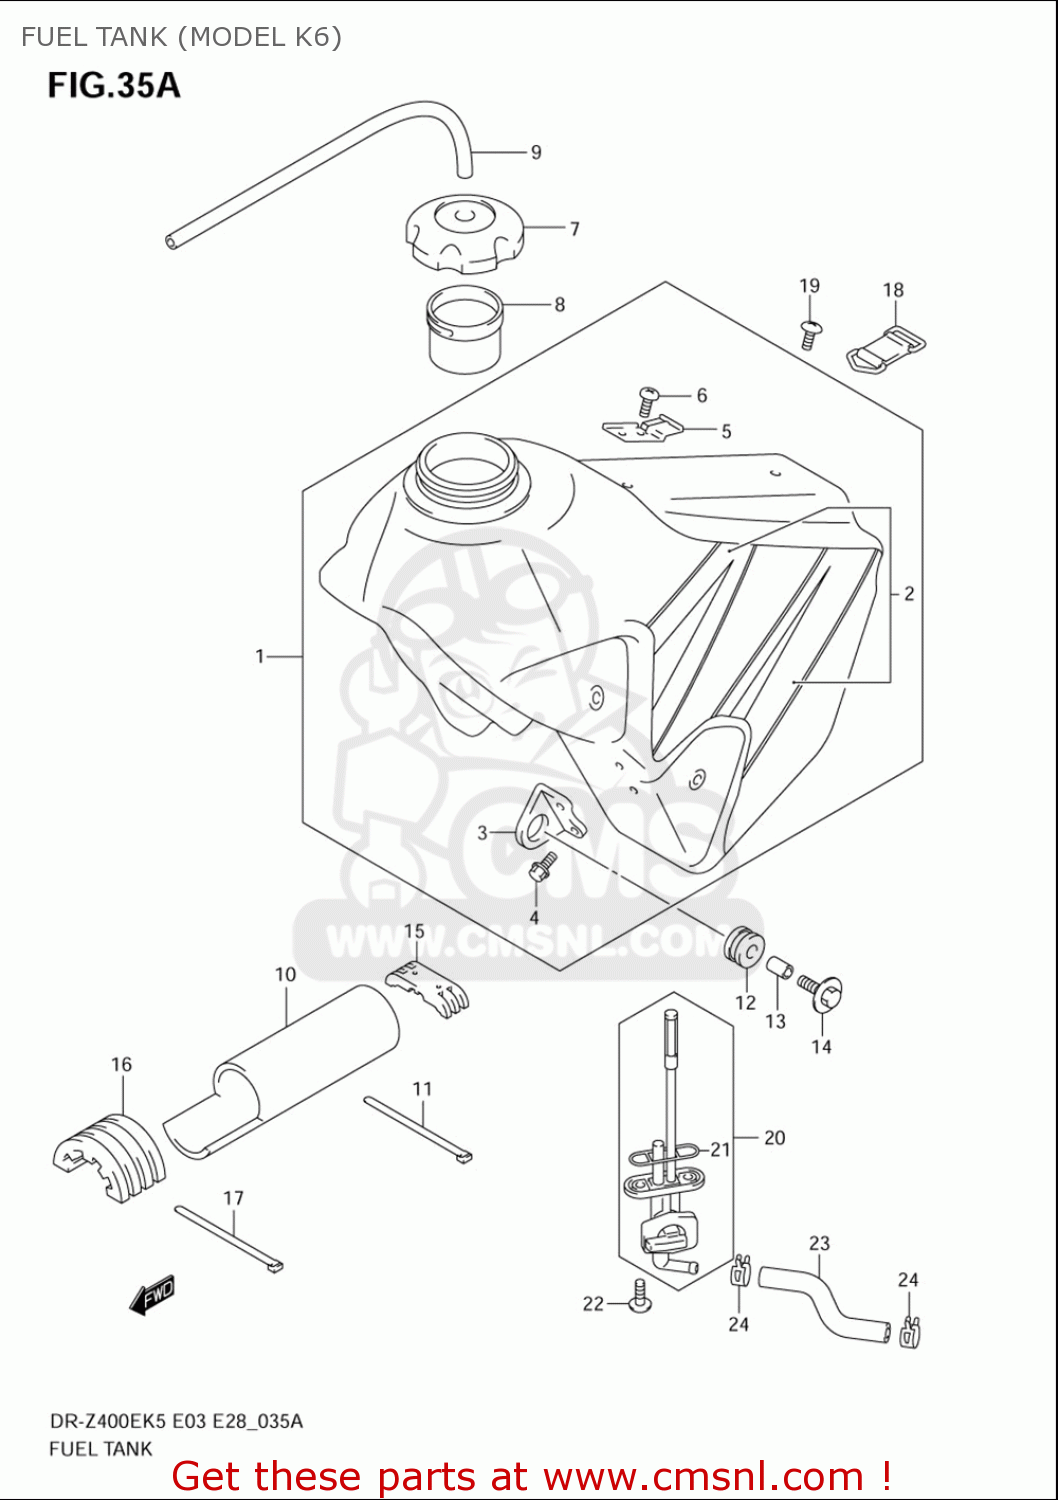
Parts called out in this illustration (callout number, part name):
1	TANK ASSY,FUEL(YELLOW)
2	TAPE SET,FUEL TANK
3	BRACKET,FUEL TANK FR
4	BOLT
5	HOOK,SEAT FR
6	SCREW
7	CAP ASSY,FUEL TANK FILLER
8	TUBE,FILLER INLET
9	HOSE(5X8.2X600)
10	SHIELD,FUEL TANK
11	CLAMP(L:300)
12	CUSHION,MUFFLER
13	SPACER(6.5X9X13.5)
14	BOLT(6X30)
15	CUSHION,FUEL TANK RR
16	CUSHION,FUEL TANK
17	CLAMP(L:300)
18	BAND,FUEL TANK RR
19	SCREW
20	COCK ASSY,FUEL
21	GASKET,JOINT (NAS)
22	BOLT
23	HOSE,FUEL
24	CLIP
